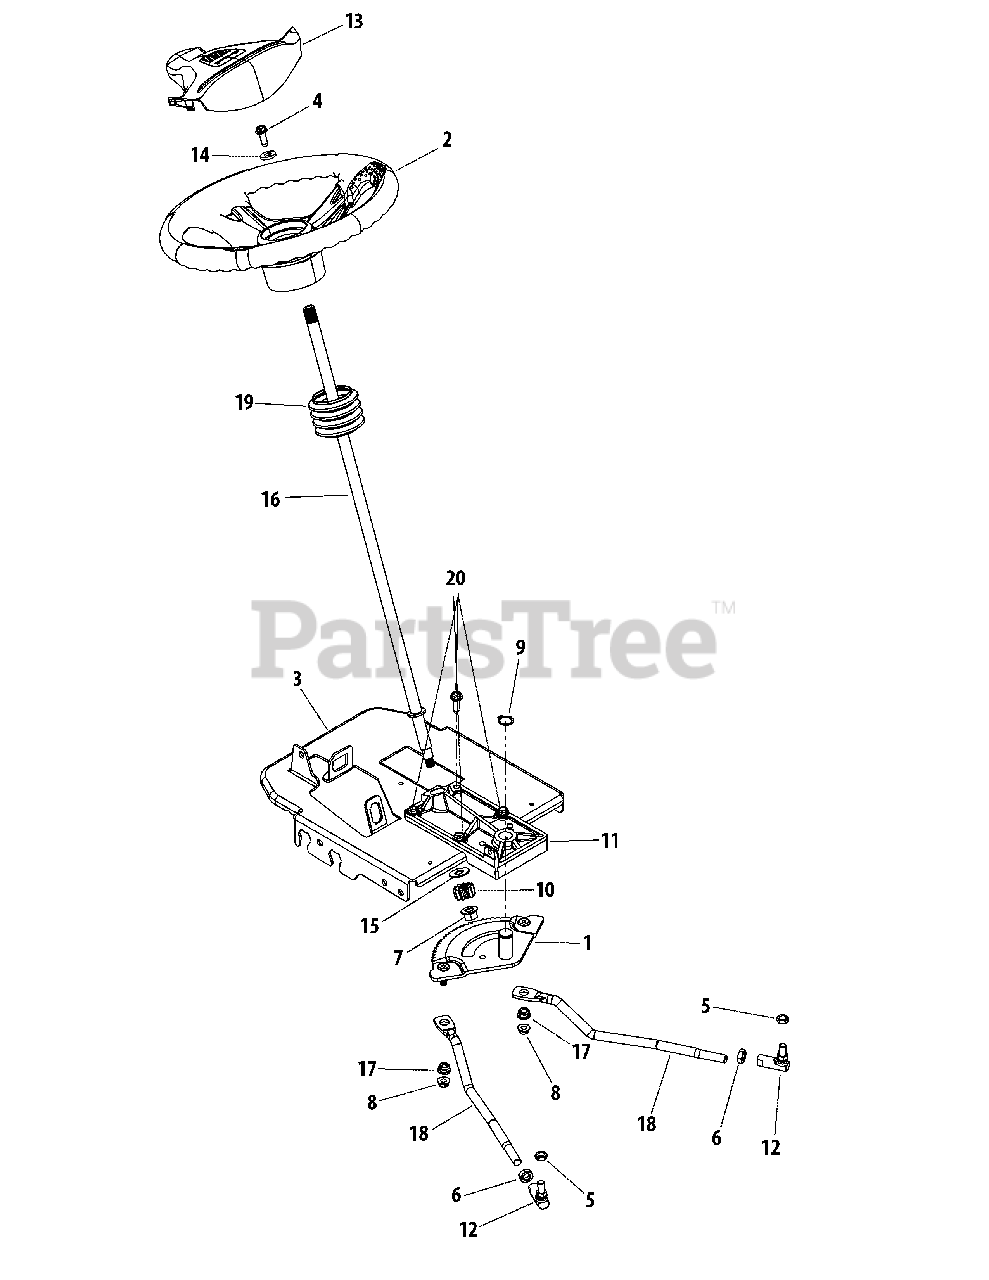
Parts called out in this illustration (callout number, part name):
1	Gear Assy, Segment
2	Wheel, Steering, Soft Grip
3	Bracket, Steering Support
4	Screw, Hx. Wash. Hd Tapp, 5/16-18 x .875
5	Nut, Hex Jam Lock, 3/8-24 Gr2
6	Nut, Hex Jam, 7/16-20 GR2
7	Nut, Flange Lock 7/16-20 GrB
8	Nut, Hex Flange Lock, 5/16-18 GR5
9	Ring, Snap, .75 Dia Shaft
10	Gear, Steering Pinion
11	Housing Assy, Steering
12	Joint, Ball, 3/8-24
13	Cover, Steering Wheel
14	Washer, Flat, .406 x .875 x .105 Thk
15	Washer, Flat, .51 x 1.12 x .03 Thk
16	Shaft, Steering, .625 x 27.10
17	Plastic Bushing, .38 ID
18	Link, Drag
19	Bellow, Steering, 2.12 Lg
20	Screw, Hx. Wash. Hd Tapp, 5/16-18 x 1.0
